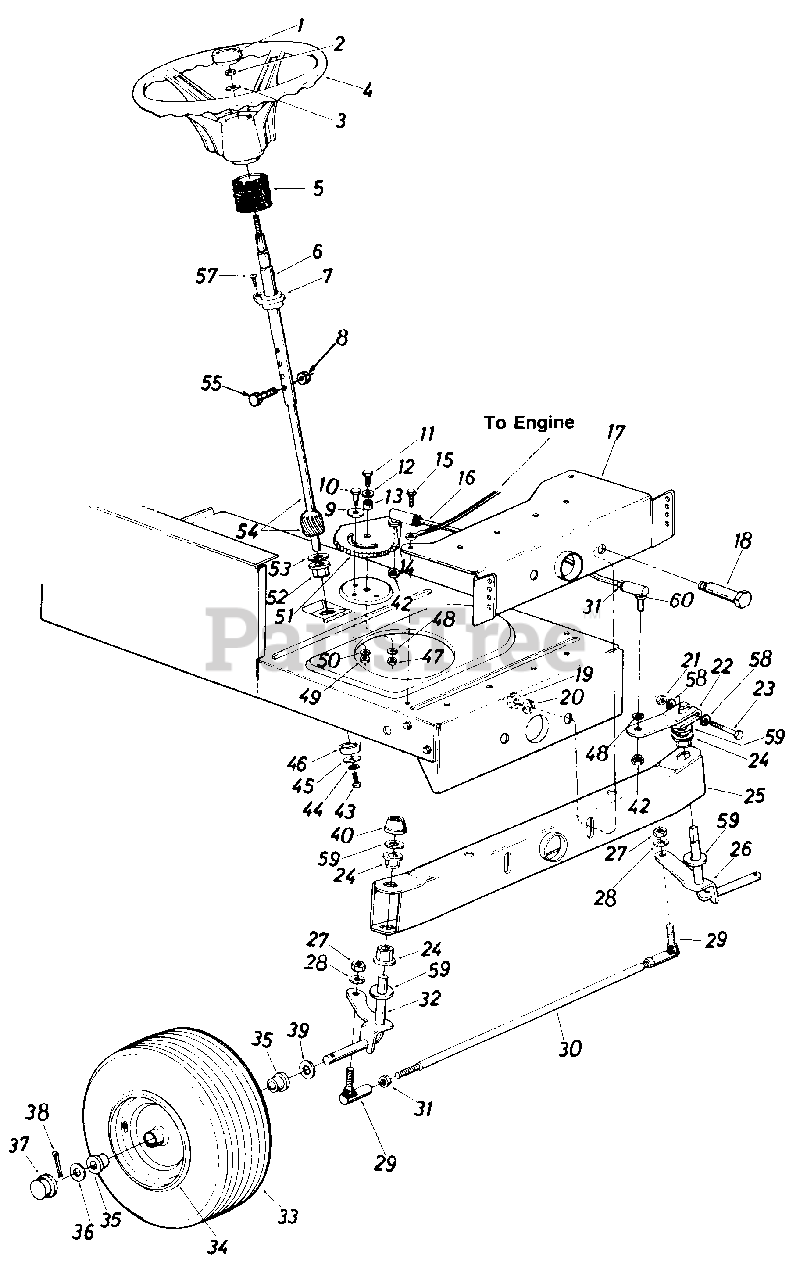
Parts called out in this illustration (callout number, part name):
1	Steering Wheel Cap
2	Hex Nut 5/16-18 Thd.
3	Belleville Wash. .345" I.D.
4	Steering Wheel
5	Steering Bellow
6	Steering Column Ass'y.
7	Flange Bearing .890 I.D. x 1.36 O.D.
8	Hex L-Nut 1/4-20 Thd.
9	Fl-Wash. .438" I.D. x 1.37"
10	Shoulder Bolt .437" Dia. x .35 Lg. 5/16-18 Thd.
11	Hex Bolt 3/8-24 x 1.0" Lg. (Grade 5)
12	Fl-Wash. .38" I.D. x 1.0"
13	Spacer .380" I.D. x .625" O.D. x .227
14	L-Wash. 3/8" I.D.
15	Hex Wash. Hd. Self-Tap Scr.
16	Steering Drag Link
17	Front Pivot Brkt.
18	Shoulder Bolt .498" Dia. x 2.04 Lg. 3/8-16 Thd.
19	Hex Nut 3/8-16 Thd.
20	L-Wash. 3/8" I.D.
21	Hex Cent. L-Nut 5/16-24 Thd.
22	Steering Arm Front Axle
23	Hex Bolt 5/16-24 x 2.00" Lg. (Grade 5)
24	Hex Flg. Brg. .634 I.D.
26	Front Axle Ass'y. L.H.
27	Hex Nut 3/8-24 Thd.
28	L-Wash. 3/8" I.D.
29	Ball Joint 3/8-24 Thd.
30	Tie Rod
31	Hex Jam Nut 3/8-24 Thd.
32	Front Axle Ass'y. R.H.
34	Front Wheel Rim Only
35	Bearing
36	Fl-Wash. .640" I.D. x 1.54" O.D.
37	Front Wheel Hub Cap
38	Cotter Pin 1/8" Dia. x 1.25" Lg.
39	Fl-Wash. .640" I.D. x .24" O.D.
40	Push Cap 5/8" Dia. Rod
42	Hex Nut 3/8-24 Thd.
43	Hex L-Bolt 5/16-18 x .62"
44	L-Wash. 5/16" I.D.
45	Fl-Wash. .344" I.D. x 1.25" O.D.
46	Spacer (Plastic)
47	Hex Nut 3/8-24 Thd.
48	L-Wash. 3/8" I.D.
49	Hex Nut 5/16-18 Thd.
50	L-Wash. 5/16" I.D.
51	Steering Gear Segment
52	Hex Flg. Brg. .634 I.D.
53	Fl-Wash. (Hardened)
54	Steering Shaft Lower
55	Hex Bolt 1/4-20 x 1.25" Lg. Special
57	Oval Hd. Cr. Sunk Scr. #10 x 5/8" Lg.
58	Wave Wash. .32" I.D. x .62"
59	Fl-Wash. (Hardened)
60	Drag Link Ball Joint 3/8-24
